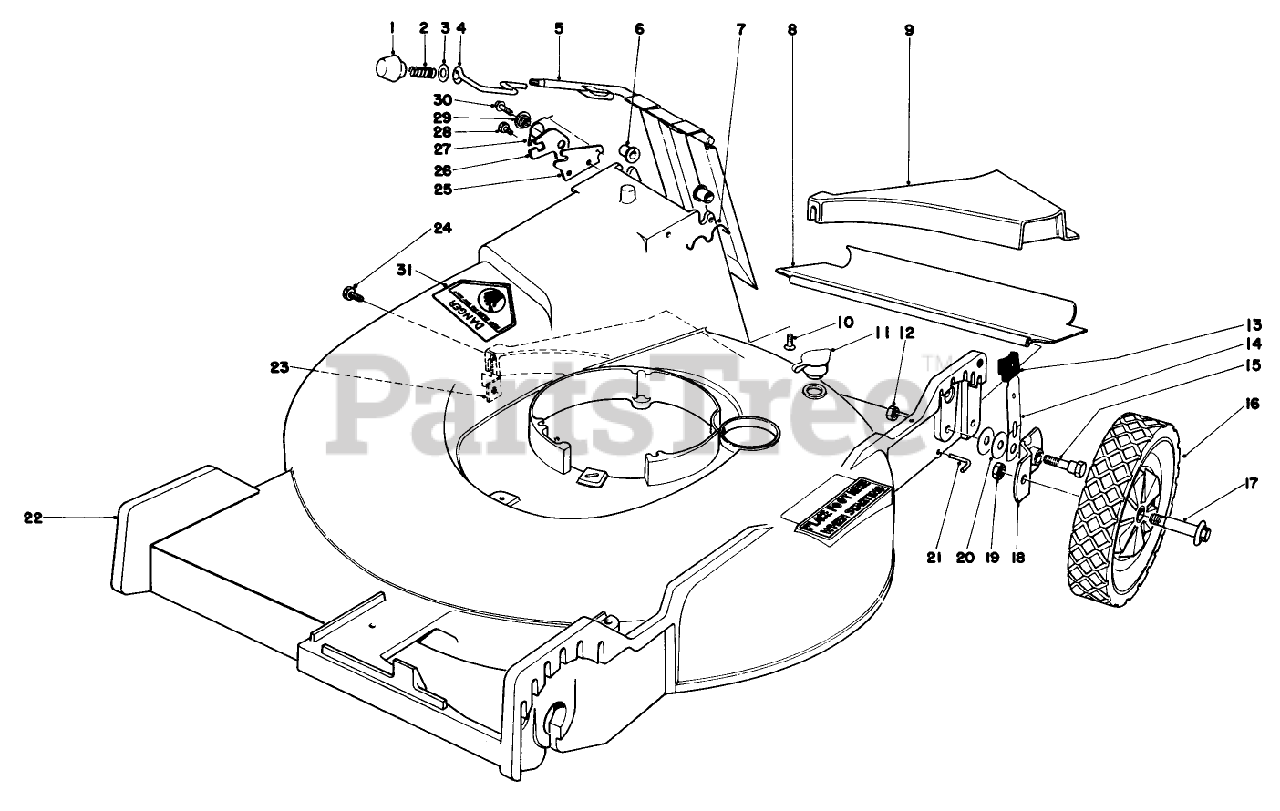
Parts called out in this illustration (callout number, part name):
2	COMPRESSION SPRING
3	WASHER
4	DOOR LATCH
6	BUSHING-NYLON
10	Flat Hd. Screw
11	WASHOUT PLUG
13	KNOB-ARM
14	SPRING ARM ASM
15	PIVOT SCREW
16	WHEEL TIRE ASM 8 IN
17	BOLT-WHEEL
18	PIVOT ARM ASM A
20	WASHER-PIVOT
21	ROD-SHIELD
24	SCREW THD 1/4 20 5/8
25	DOOR LATCH PLATE
28	SCREW-HWH
31	DECAL-DANGER
